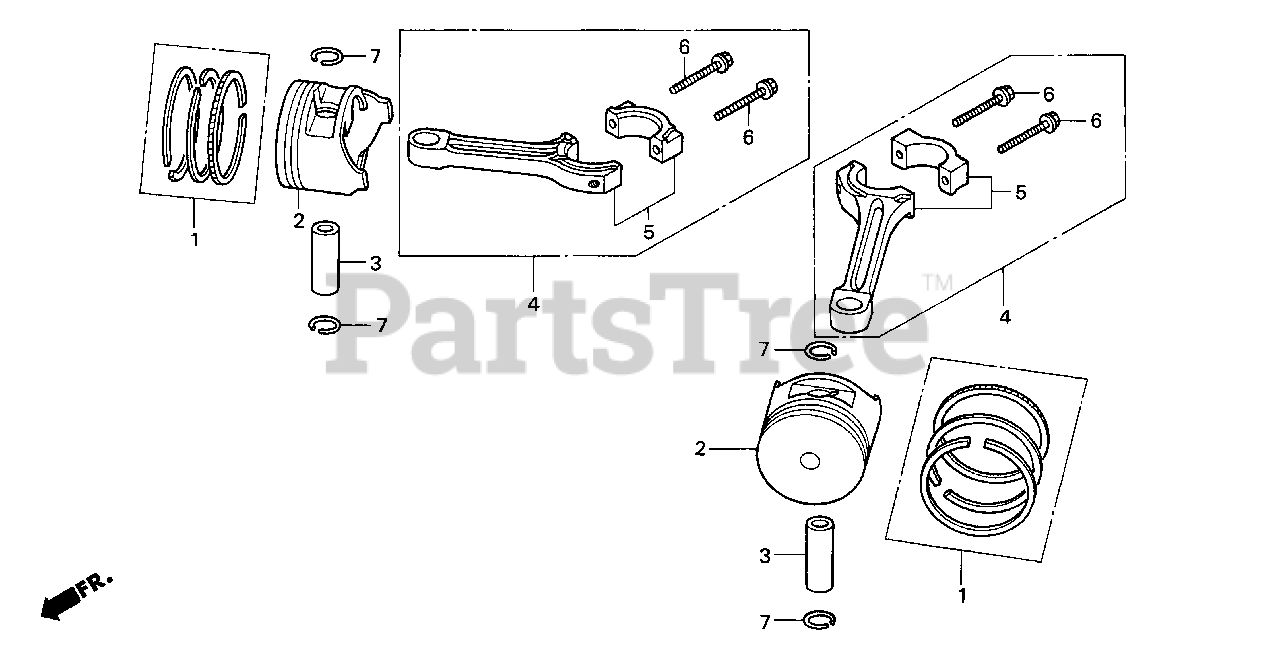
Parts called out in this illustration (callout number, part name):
1	RING SET, PISTON (STD)
1	RING SET, PISTON (OS 0.25)
1	RING SET, PISTON (OS 0.50)
1	RING SET, PISTON (0.75)
2	PISTON (STD)
2	PISTON (OS 0.25)
2	PISTON (OS 0.50)
2	PISTON (0.75)
3	PIN, PISTON
4	ROD ASSY., CONNECTING
5	ROD ASSY., CONNECTING
6	BOLT, CONNECTING ROD (6X37)
7	CLIP, PISTON PIN (18MM)
